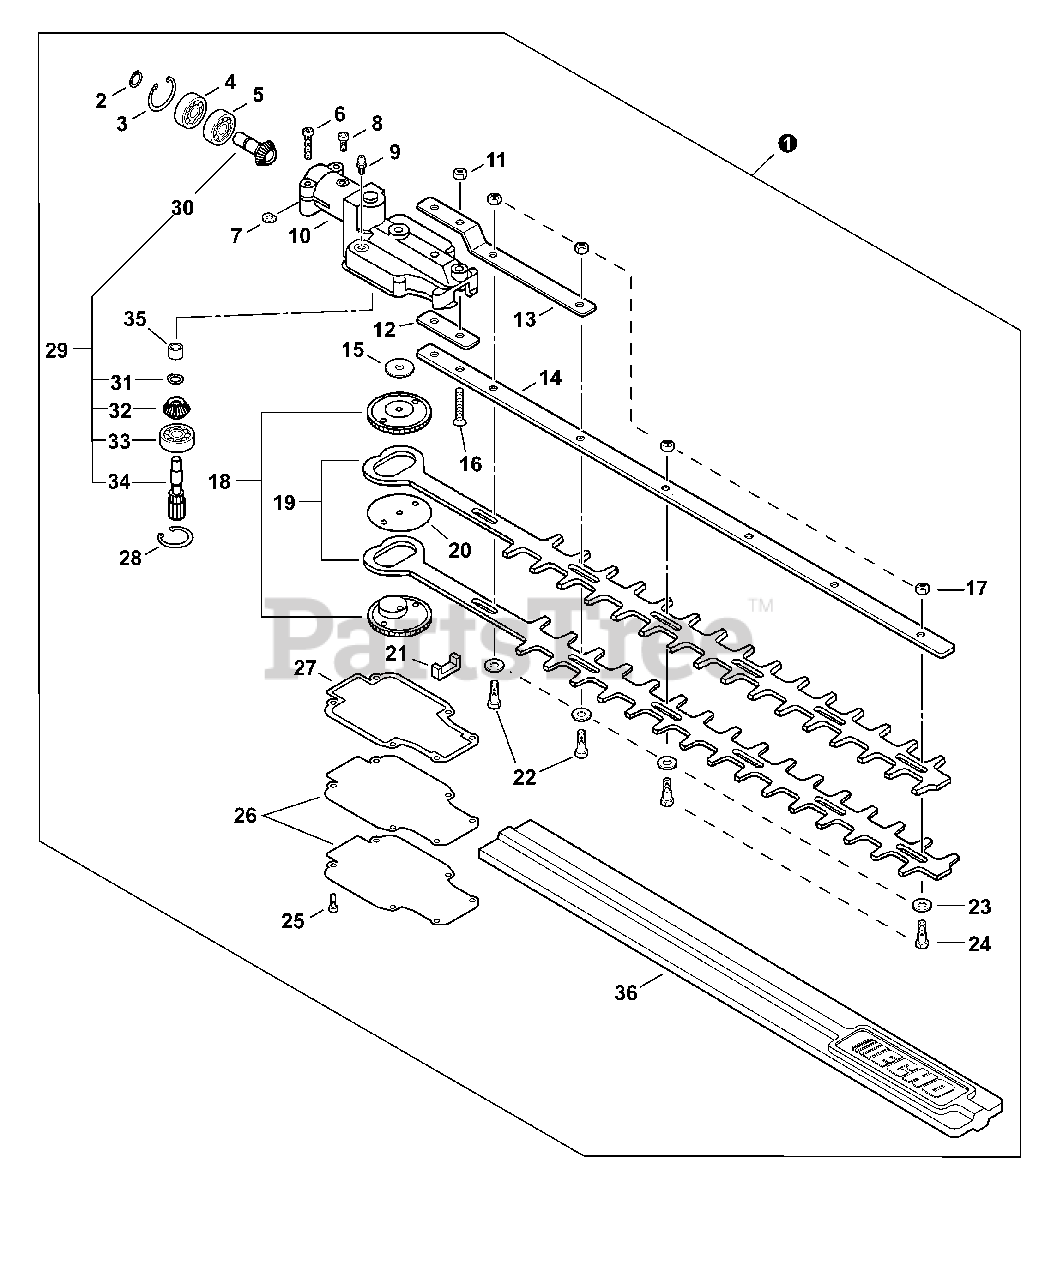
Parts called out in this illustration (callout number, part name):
1	GEAR CASE ASSY
2	RING, SNAP Ø12
3	RING, RETAINING Ø24
4	BEARING, BALL 6901Z
5	BEARING, BALL 6901
6	BOLT 5×28
8	BOLT, TORX 5×12
9	FITTING, GREASE
10	CASE, GEAR - UPPER
11	NUT, HEX M6
12	SPACER
13	PLATE, ANGLE
14	SUPPORT, BLADE
15	WASHER 6.5×30×0.2
16	SCREW 6×35
18	GEAR, SPUR
20	WASHER 6.7×54×0.38
22	BOLT 6×20
23	WASHER 6.5×15.5×0.6
25	BOLT, TORX 4×12
26	LID, GEAR CASE
27	GASKET, GEAR CASE
28	RING, RETAINING Ø24
29	GEAR KIT, SPUR
30	GEAR, BEVEL
31	RING, RETAINING
32	GEAR, BEVEL
33	BEARING, BALL 6901
34	GEAR, PINION
35	BEARING, NEEDLE
36	SCABBARD
